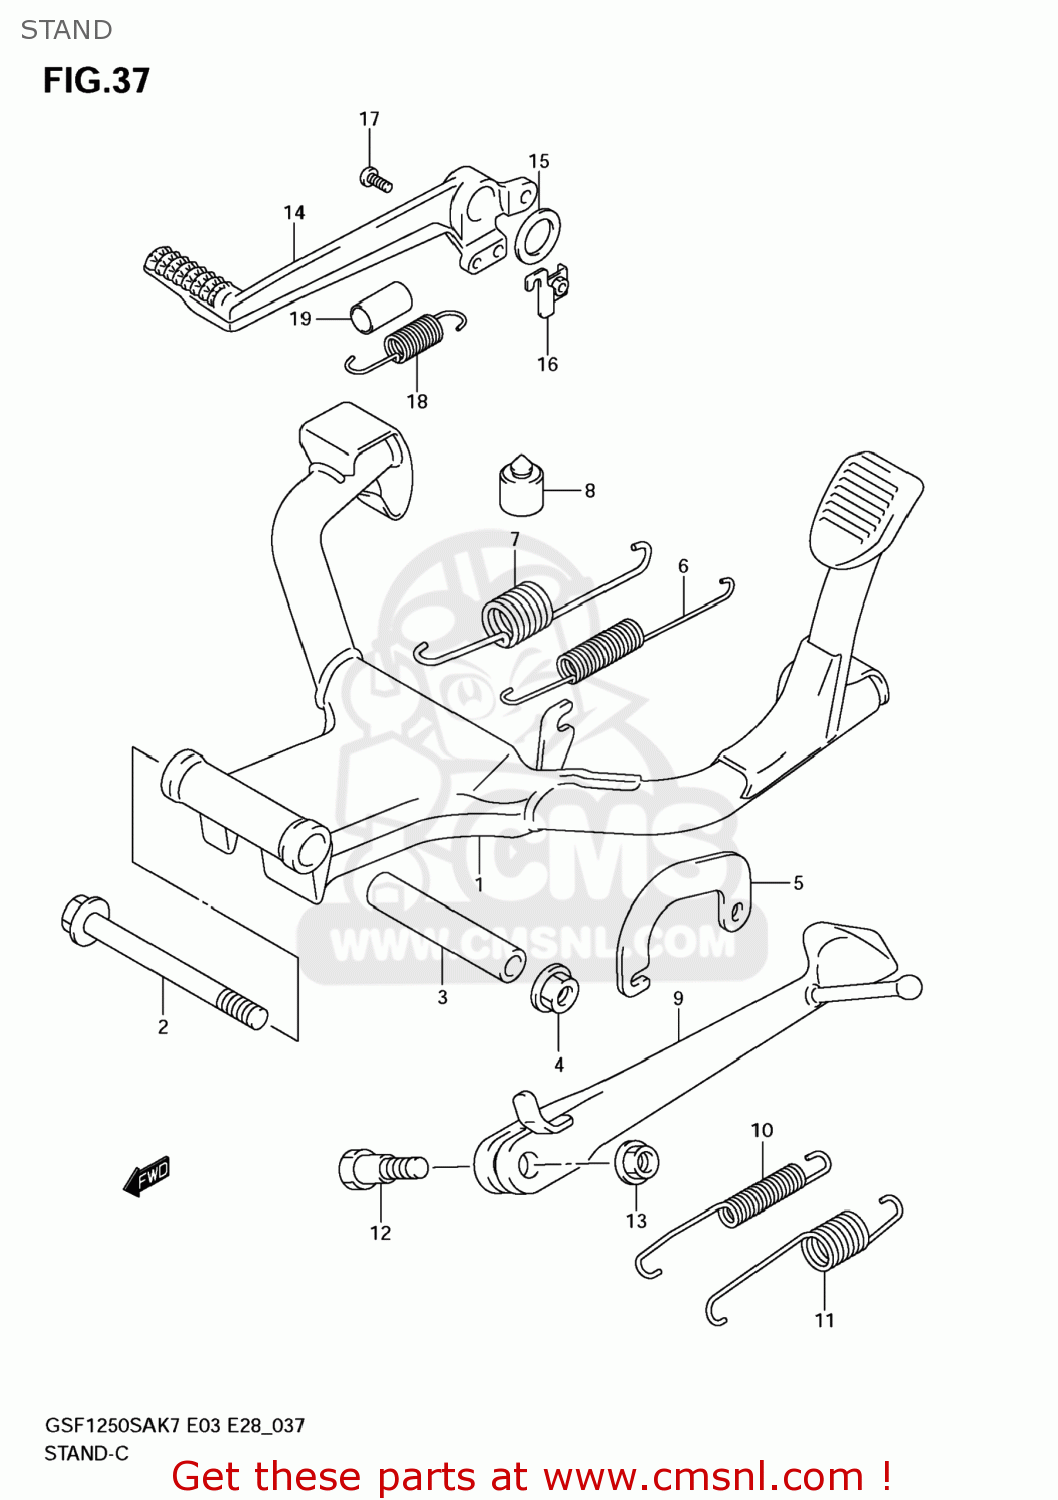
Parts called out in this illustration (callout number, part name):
1	STAND,CTR
2	BOLT(10X105)
3	SPACER,CTR STAND
4	NUT
5	HOOK,CTR STAND SPRING
6	SPRING
7	SPRING
8	CUSHION
9	STAND,PROP
10	SPRING
11	SPRING
12	BOLT(10X38)
13	NUT,PROP STAND
14	PEDAL,BRAKE
15	WASHER(18X24X1)
16	BRACKET,STOP LAMP SWITCH SPR
17	SCREW
18	SPRING
19	TUBE,BRAKE SPRING GUIDE
